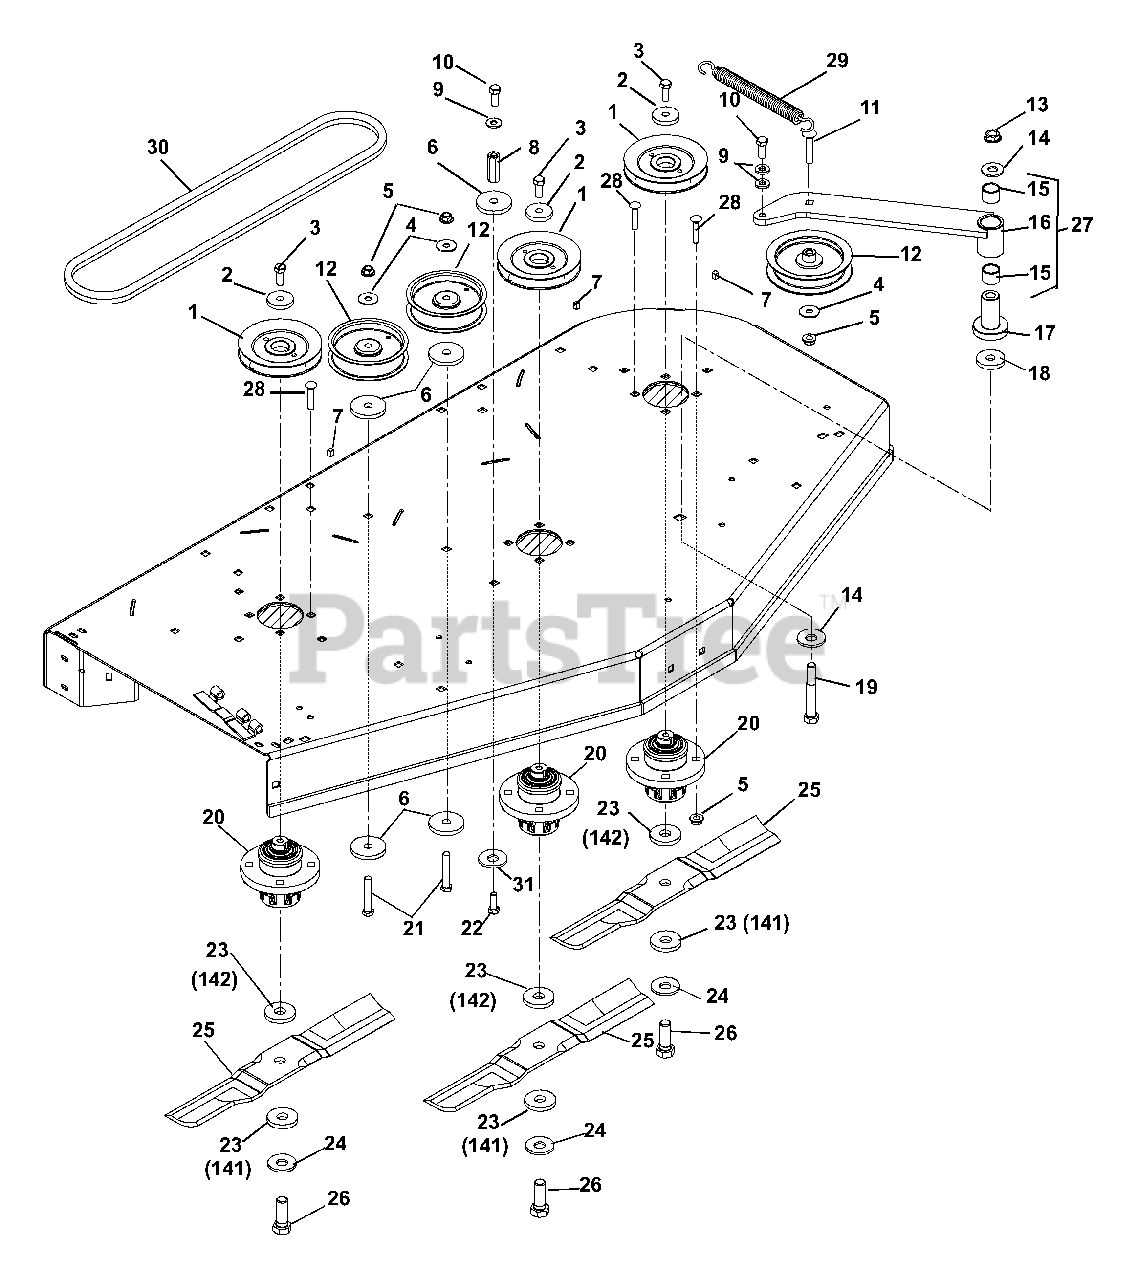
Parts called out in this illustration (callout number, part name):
1	SHEAVE, 4.75 DIA A-SECTION
2	WSHR,FLT STL.406X1.50X.245YWZC
3	BLT-HEX .38-16X1.0 GR8 YZ EP30
4	WSHR-FL-STL .375X1.125X.065YWZ
5	@NUT-LK-NYL-FLG .38-16 YWZC
6	WSHR-FL-STL .469X2.00X.25 YWZC
7	KEY, SQ .25 X .38 X .25
8	NUT COUPLING .375-16X1.75
9	@WSHR-FL-STL.38X.875X.083 YWZC
10	BLT,SHLDR EP .38-16X.30 HEX YZ
11	@BLT-RDHDSQNK .38-16X2.00 G5YZ
12	IDLER, FLAT .38X4.00X1.06
13	@NUT-LK-TOP-FLG .50-13 YWZC
14	WSHR-FL-STL .531X1.250X.10 YWZ
15	BRG, 1.00 X 1.12 X .75
16	WMT, IDLER ARM
17	BEARING, PEDESTAL
18	WASHER, FLAT .531X3.000X.25
19	@BLT-HEX .50-13X3.75 GR5 YWZC
20	ASSEMBLY, SPINDLE
21	@BLT-HEX .38-16X2.25 GR5 YWZC
22	BLT-HEX .38-16X1.0 GR8 YZ EP30
23	WSHR-FLT .640X1.75X.250 YWZC
24	WSHR-BLVL .669X1.535X.138
25	BLADE, MOWER (16.19")
25	BLADE, 15.50"
26	BLT-HEX .62-18X1.75 GR8 YWZC
27	ASSM, IDLER ARM
28	@BLT-RDHDSQNK .38-16X1.50 G5YZ
29	SPRING, EXTENSION (DECK IDLER)
30	V-BELT, HA-WRAPPED
31	WSHR-FL-STL .380X1.50X.125YWZC
